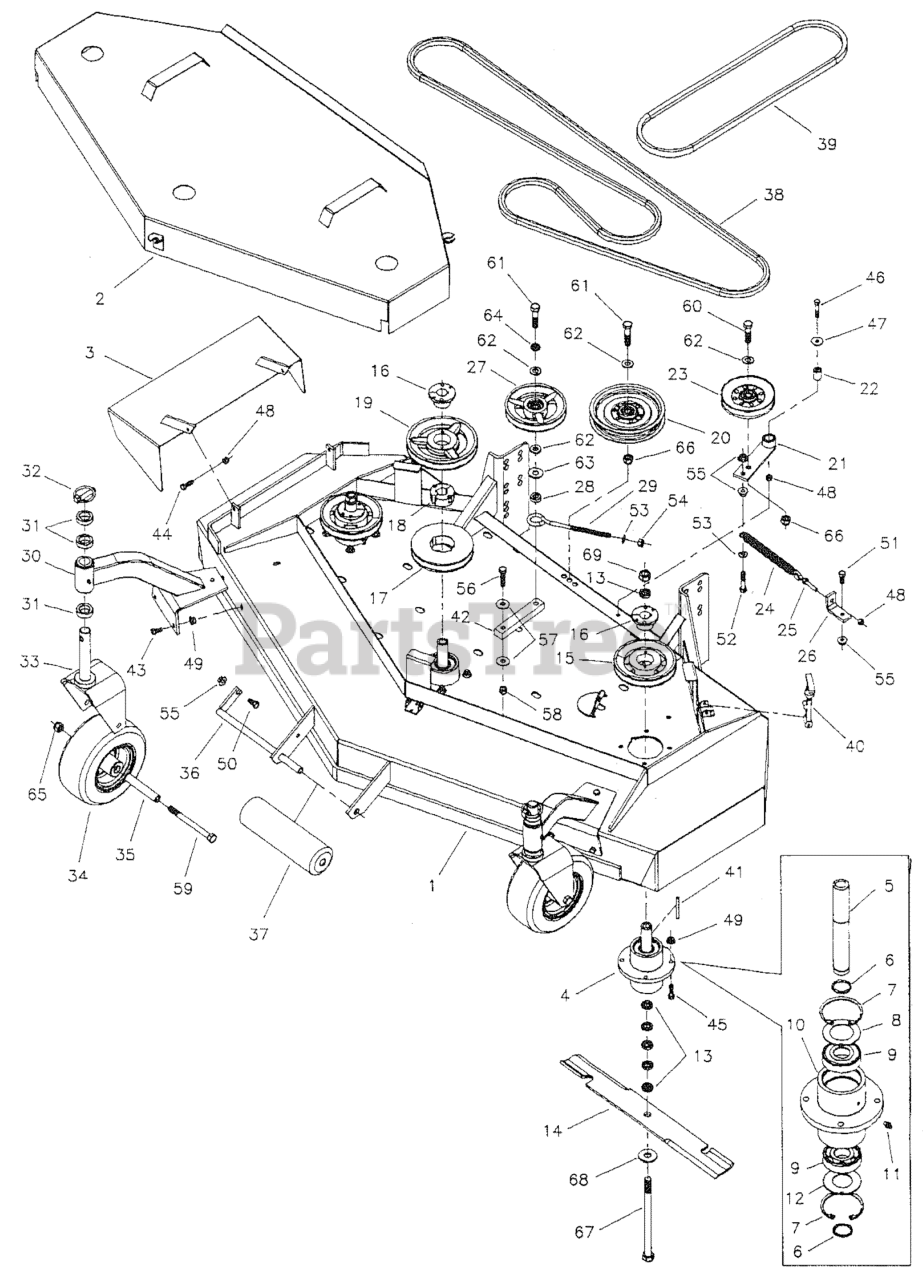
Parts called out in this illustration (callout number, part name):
1	61" Cutter Deck
2	61" Guard
3	CHUTE, DISCHARGE WELDMENT
4	Spindle Assembly
5	Shaft, Spindle
6	Snap Ring, External
7	Snap Ring, Internal
8	Spindle Washer-Top
9	Bearing
10	Housing, Spindle
11	Grease Fitting
12	Spindle Washer-Bottom
13	Spacer, Blade
14	Blade, 21"
15	Pulley, Spindle
16	Bushing, Tapered Hub
17	Pulley, Taper Lock
18	Bushing, Taper Lock
19	Pulley, Spindle
20	Pulley, Backside Idler
21	Ann, Idler w/ Bushing
21	Bushing, Brass
22	Spacer, Pivot
23	Pulley, V-Idler
24	Spring, Extension
25	Eyebolt
26	Anchor, Spring
27	Idler Pulley Assembly
27	Pulley, Idler
27	BEARING, BALL 11/16X1-9/16X15/32
27	Insert, Bearing
27	Snap Ring, Internal
28	Spacer, Idler
29	Eyebolt, 3/8" x 8"
30	Mount, Deck Caster
30	BUSHING, FLANGE
30	Grease Fitting
31	Spacer, Caster
32	Pin, Lynch
33	Yoke, Caster
34	Tire, Caster
35	Axle, Caster Wheel
37	Roller
38	Belt, Blade Spindle
39	Belt, Deck Drive
40	Latch, Rubber
41	KEY, 1/4 SQ X 2-1/2
42	Arm, Idler
43	BOLT, 5/16-18 X 3/4 GD5
44	Bolt, 5/16-18 x I" GD.5
45	Bolt, 5/16-18 x 1-114" GD.5
46	Bolt, 5/16-18 x 1-3/4" GD.5
47	Washer, 5/16" Fender
48	Nut, 5/16-18 Hex Nylon Lock
49	NUT, 5/16-18 HEX SERRATED FLANGE (LARGE)
50	BOLT, 3/8-16 X 3/4" GD5 CZ
51	BOLT, 3/8-16 X 1" GD5 CZ
52	BOLT, 3/8-16 X 2, GD5, CZ
53	WASHER, 3/8 SAE
54	NUT, 3/8-16 HEX NYLON LOCK
55	Nut, 3/8-16 Serrated Flange
56	BOLT, 7/16-20 X 1-3/4" GD.5
57	Washer, 7/16" SAE
58	Nut, 7/16-20 Hex Nylon Lock
59	Bolt, 1/2-13 x 5-1/2" GD.5
60	Bolt, 112-20 x 2" GD.5
61	BOLT, 1/2-20 X 2-1/4 GD5 CZ
62	WASHER, 1/2 SAE
63	Washer, 112" USS
64	Washer, 1/2" Lock
65	NUT, 1/2-13 HEX NYLON LOCK
66	NUT, Hex, Nylon Lock, 1/2-20
67	Bolt, 5/8-11 x 9-1/2" GD.5
68	Washer, 5/8" USS
69	Nut, 5/8-11 Hex
